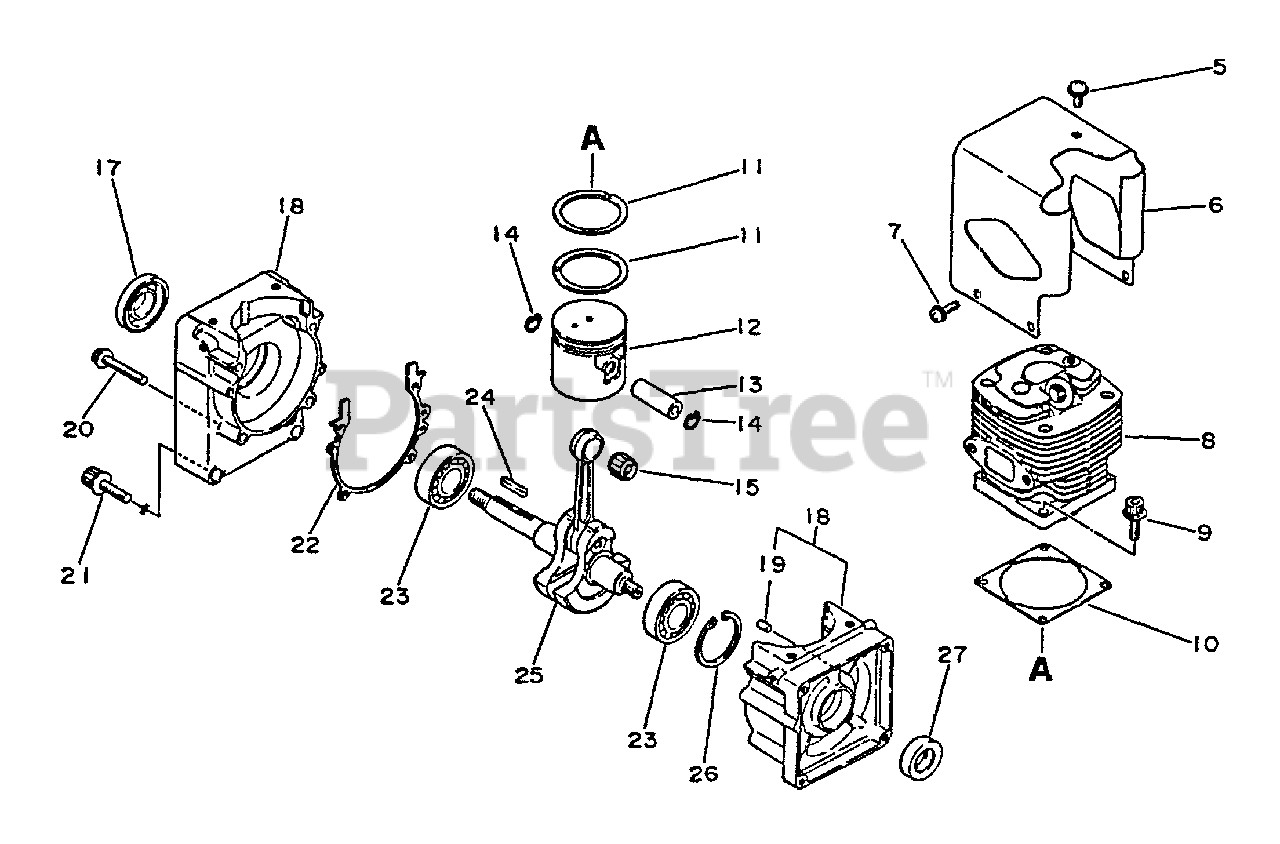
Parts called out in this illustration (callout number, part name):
5	SCREW - 5X10
6	COVER, CYLINDER - BLACK
7	SCREW - 4X10
8	CYLINDER
9	SCREW - 5X20
10	GASKET
11	RING, PISTON
12	PISTON
13	PIN, PISTON
14	RING, RETAINING - 8
15	BEARING, NEEDLE
17	SEAL, OIL
18	CRANKCASE KIT
19	PIN - LOCATING
20	SCREW - 5X30
21	SCREW - 6X20
22	GASKET, CRANKCASE
23	BEARING, BALL - 6202
25	CRANKSHAFT ASSY
26	RING, RETAINING - 35
27	SEAL, OIL
